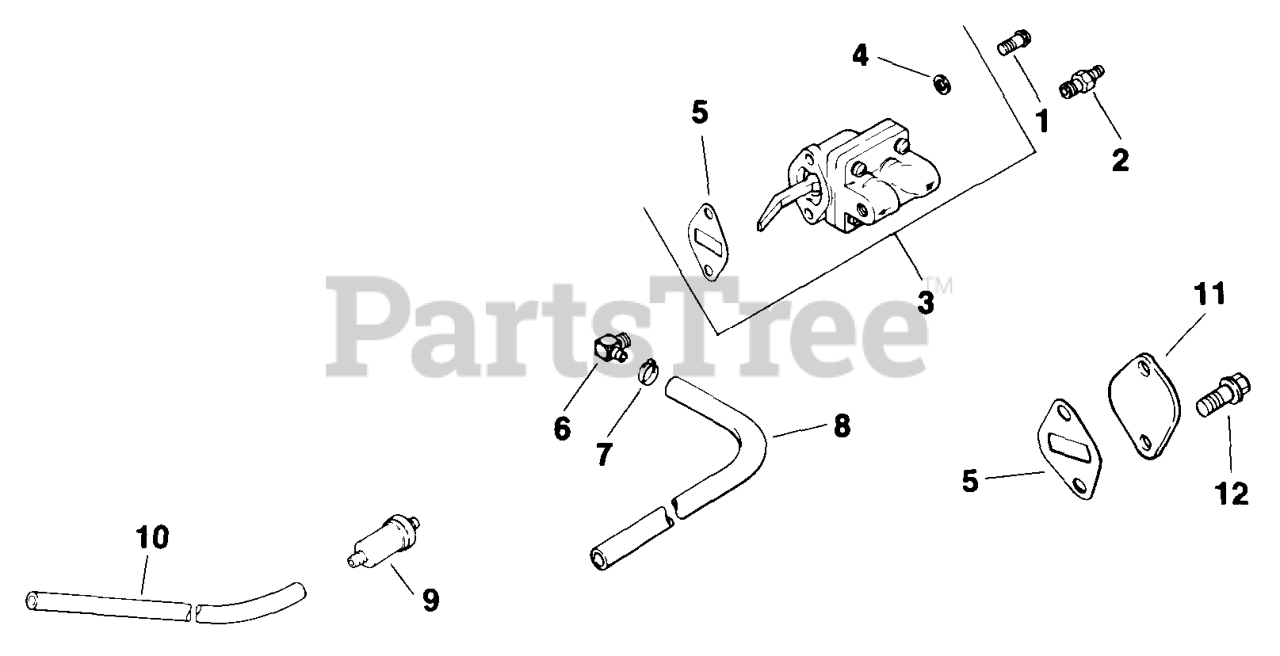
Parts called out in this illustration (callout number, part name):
1	Screw, Pozidriv T.H. 1/4-20x5/8"
2	Connector, Straight Hose
3	Pump Assembly, Fuel
4	Washer, Plain 1/4"
5	Gasket, Fuel Pump
6	Connector, 90 Degree Hose
7	Clamp, Hose
8	Line, Fuel 8"
